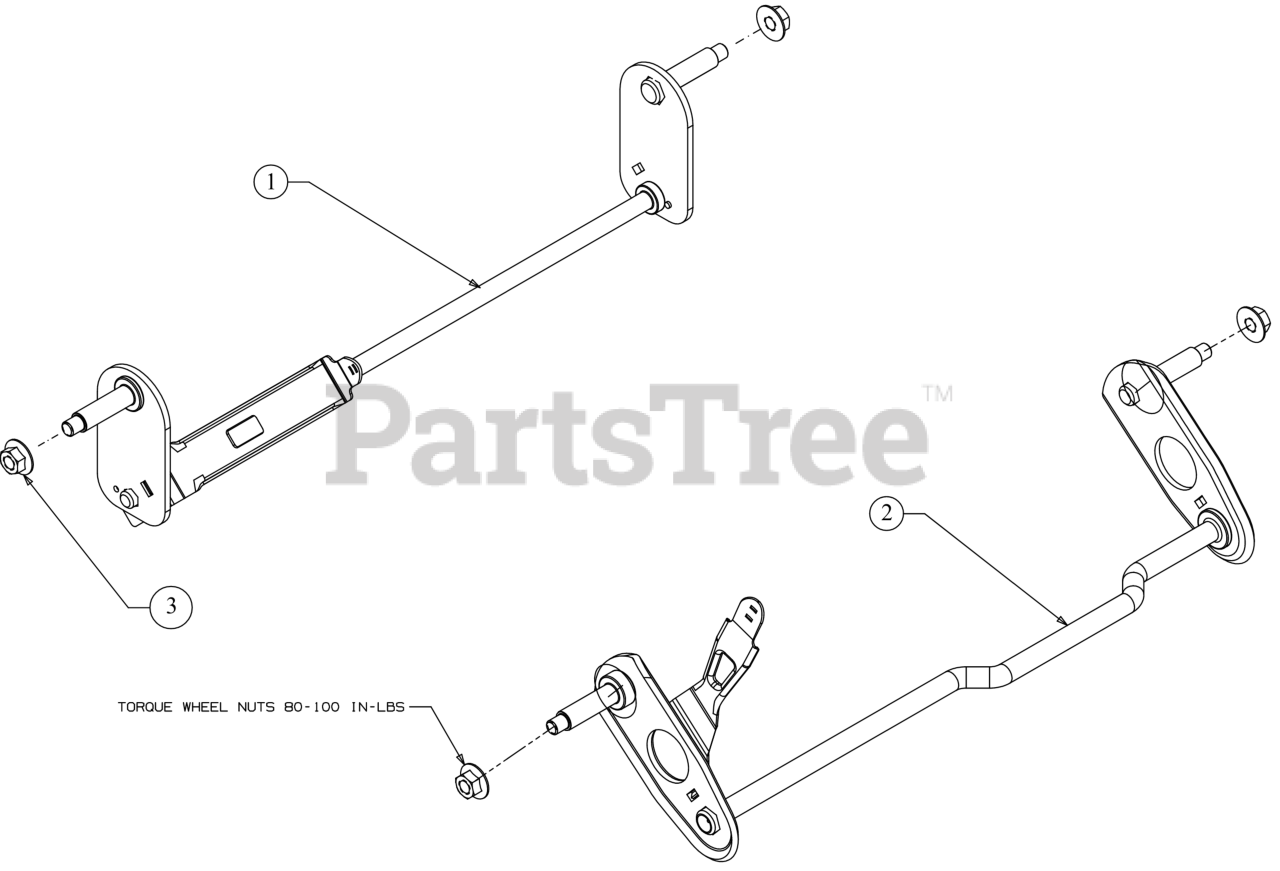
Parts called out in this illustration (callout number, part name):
1	11" REAR AXLE ASSEMBLY
2	8" FRONT AXLE ASSEMBLY
3	FLANGE LOCK NUT
